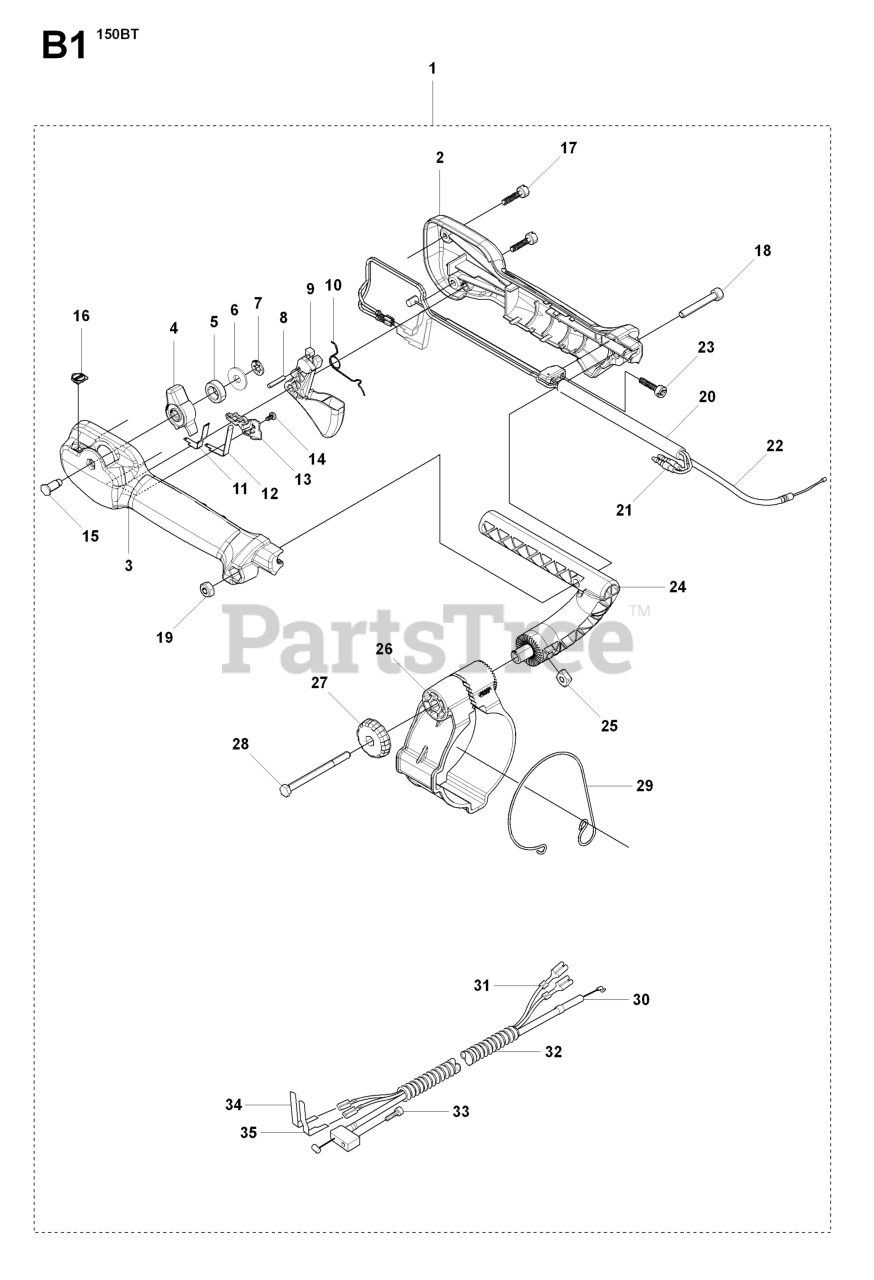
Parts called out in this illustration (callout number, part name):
1	TUBE.LEVER.CNTL.ASM.ZTR.RT.SVC
2	TUBE.LEVER.CNTL.ASM.ZTR.LT.SVC
3	BRACKET.CONTROLS.ZTR.X431
4	BEARING, FLANGE
5	LEVER CONTROL PIVOT
6	CONTROL.LEVER.HANDLE
7	SPACER.PIVOT.CONTROL
9	BLOCK TRACKING CONTROL ZTR
10	BOOT.STEERING.LEVER
11	CONTROL.BOOT.FLANGE.X431
12	ROD.ASM.RH.ADJUSTABLE
13	ROD.ASM.LH.ADJUSTABLE
14	RETAINER.CLIP.SPRING.S
15	PURCHASE THE COMPLETE LEVER
16	HCS 1/2-13 X 2-3/4 GD 5 ZD
17	SCREW.SHAKEPROOF.1.25.BLACK
18	HHFS 5/16-18 X 3/4
19	HCS 5/16C X 1
20	BUTTONHEAD.5/16-18X1.125.BLACK
21	SCREW 5/16-18 X 1 3/4 BTN-HD
22	NUT 1/2-13 HEX JM NYL
23	5/16-18 NYLOC FLANGE NUT
24	NYLOCK.NUT.5/16-18 BLACK
25	NUT 5/16C WHIZ
26	NUT.71038.31-18.HEX.NYLOCK
27	WASHER.11/32ID.11/16OD.116THIC
28	WASHER
